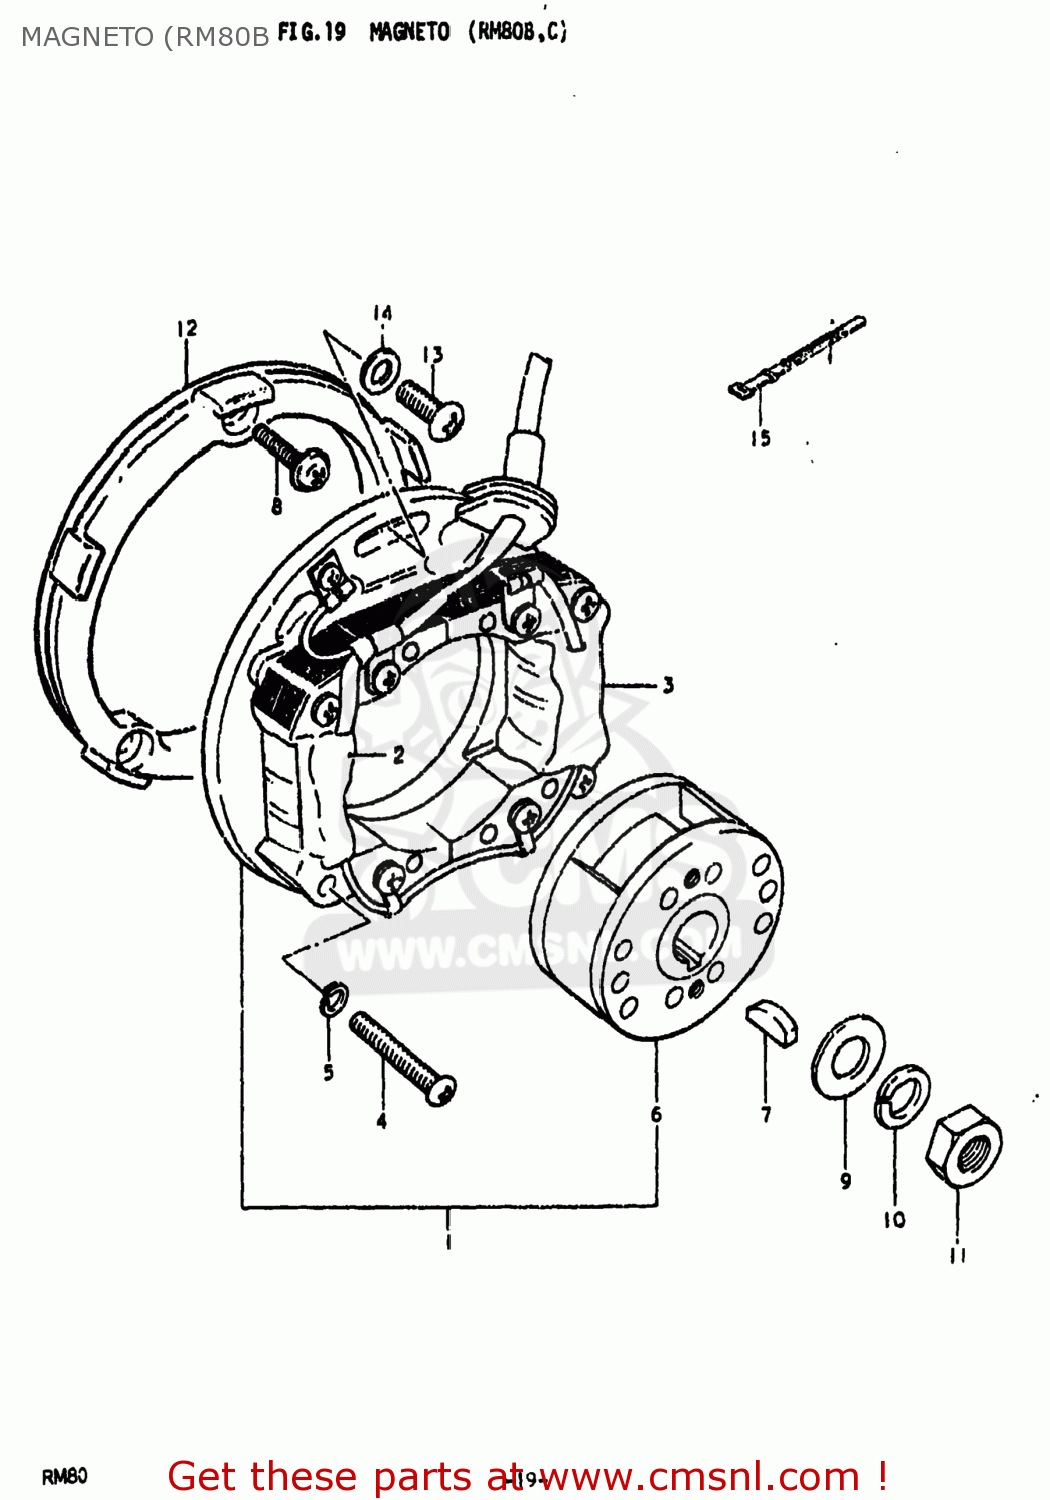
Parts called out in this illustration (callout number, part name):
1	MAGNETO ASSEMBLY
2	COIL,PULSER
3	COIL,PRIMARY
4	SCREW
5	LOCK WASHER
6	ROTOR ASSEMBLY
7	KEY 4MM
8	SCREW(5X14)
9	WASHER
10	LOCK WASHER
11	NUT (10MM)
13	SCREW
14	WASHER
15	CLAMP
